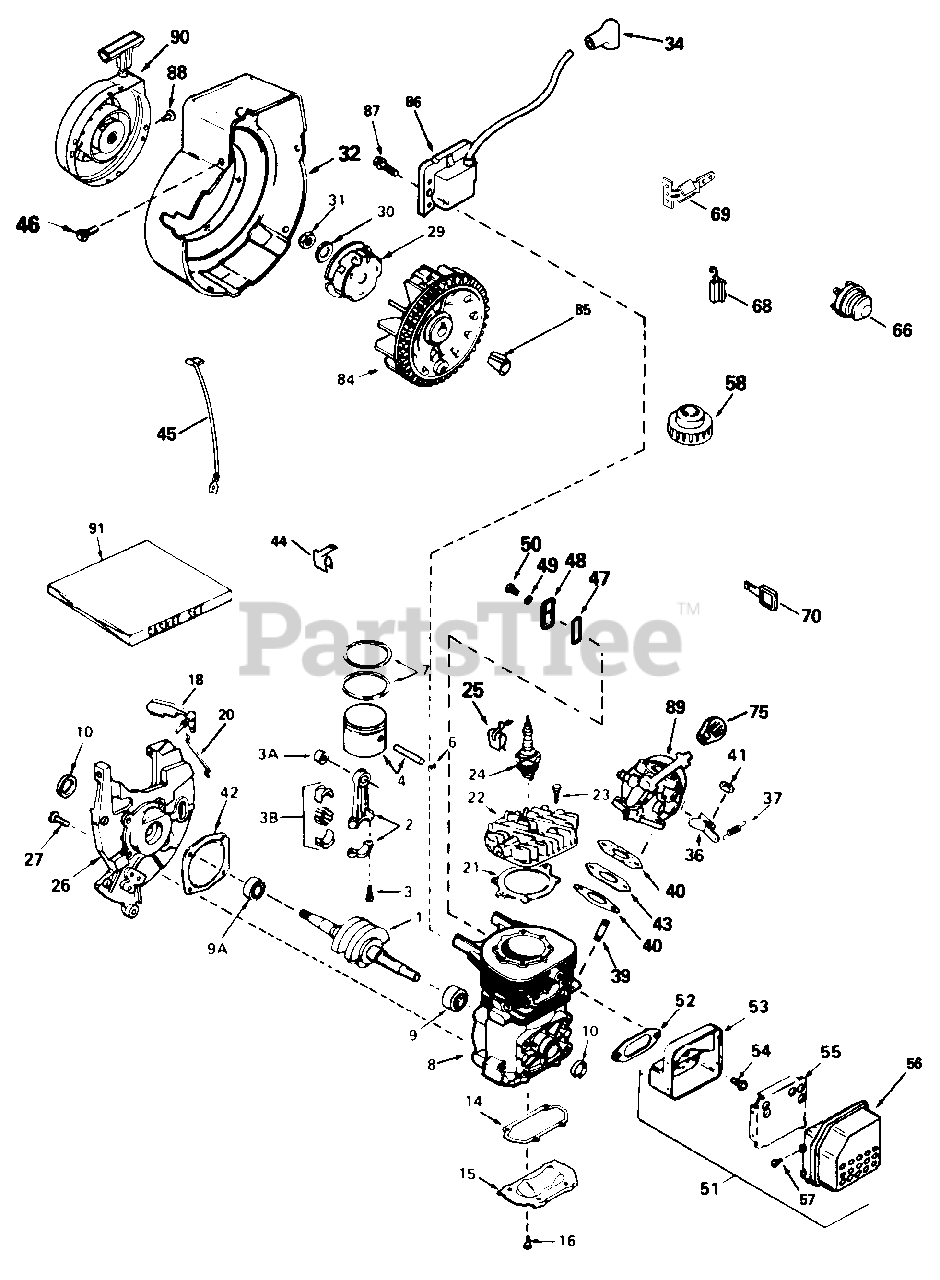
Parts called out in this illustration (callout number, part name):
1	Crankshaft
2	Rod Ass'y., Connecting
3	Screw, Connecting Rod
3A	Bearing, Cartridge
3B	Bearing & Liner Set, Needle
4	Piston and Pin Ass'y.
6	Ring, Piston Pin Retaining
7	Ring Set, Piston
8	Block Ass'y., Cylinder
9	Bearlng. Needle
9A	Bearlng, Ball
10	Seal, Crankshaft
14	Gasket, Cover
15	Plate, Cover
16	Screw, Pan Flex Hd., 10-24 X1/2
18	Vane Ass'y., Air
20	Link, Governor
21	Gasket, Cylinder Head
22	Head, Cylinder
23	Screw, Pan Flex Hd., 1/4-20 x 3/4
24	Plug, Spark
26	Base Ass'y., Blower Housing
27	Screw, Torx Pan Hd., 1/4-20 x 5/8
29	Cup, Starter
30	Washer, Spring
31	Nut, Flywheel
32	Housing, Blower
34	Cover, Spark Plug
36	Lever, Adjusting
37	Spring, Adjusting Lever
39	Stud, Carburetor
40	Gasket, Carburetor
41	Nut, Hex, 1/4-28
42	Gasket, Housing Base
43	Spacer, Carburetor
44	Clip, Spring
45	Wire, Ground
46	Screw, Hex Washer Hd. Powerlok Thread, 1/4-20 x 3/8
47	Gasket, Cover
48	Cover Ass'y., Compression Release
49	Washer, Flat No. 10
50	Screw, Pan Flex Hd., 10-24 x 1/2
51	Muffler Ass'y.
52	Gasket, Muffler
53	Base, Muffler
54	Screw, Hex Washer Hd., 1/4-20 x 5/8
55	Baffle, Muffler
56	Cap, Muffler
57	Screw, Hex Hd. Self-Tap, 8-18 x 3/8
66	Primer Ass'y.
68	Terminal Ass'y.
69	Bracket, Key Switch
70	Key, Switch
75	Knob, Control
85	Sleeve, Flywheel
86	Solid State Ass'y.
87	Screw, Hex Hd. Sems, 10-24 x 1
88	Screw, Wash. Hd. 8-32 x 1/2
89	Carburetor
90	Starter Ass'y., Rewind
91	Gasket Set
